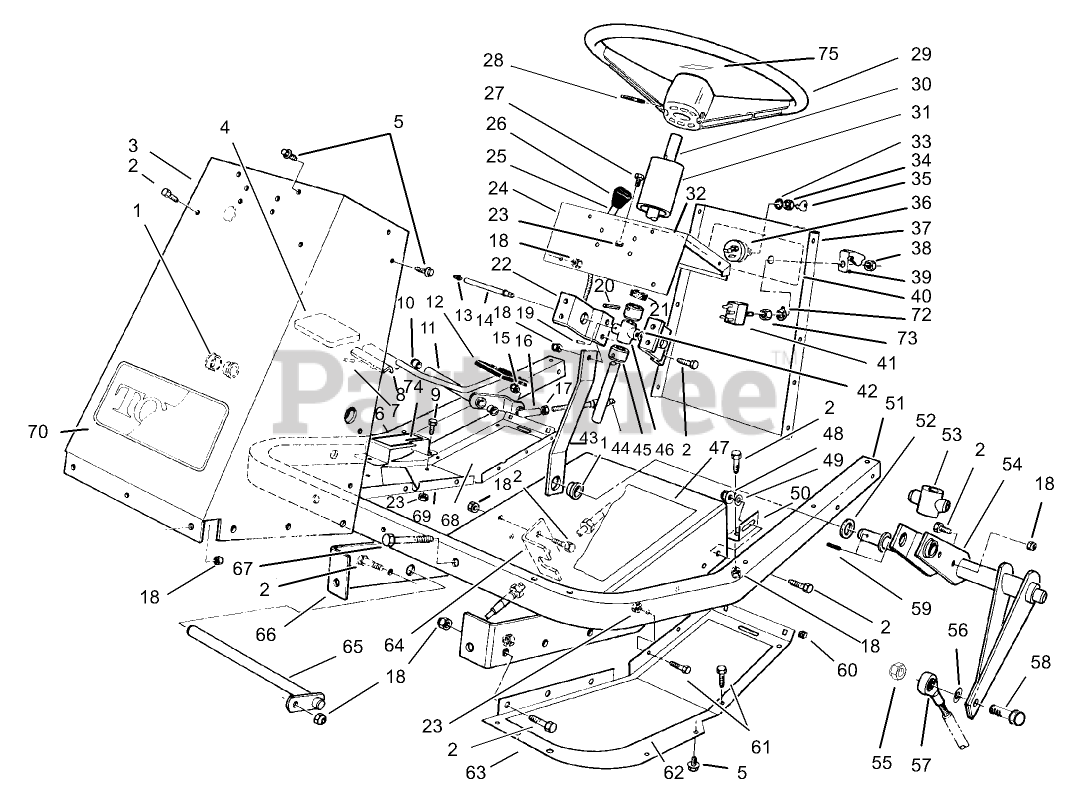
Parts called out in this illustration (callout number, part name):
1	BEARING-FLANGE
2	SCREW-HH
3	Tower-Front
4	FORWARD PEDAL PAD
5	SCREW-HHFTF
6	Footrest-Pedal
7	PIN-ROLL
8	ACCELERATOR PEDAL
9	SCREW-HH
10	BUSHING-FLANGE
11	Pedal-Traction (Incl. Ref. #10)
12	REVERSE PAD
13	FITTING-GREASE
14	TUBE ZERK
15	NUT-LOCK
16	JOINT-BALL
17	NUT-JAM
18	NUT-LOCK, NI
19	3/32 X 9/16 ROLL PIN
20	PIN-SPRING
21	COVER-DUST
22	BRG SUPT BRKT
23	NUT-LOCK, NI
24	Tower-Top
25	CONTROL-CHOKE,THROTTLE
27	SCREW-HH
28	PIN-ROLL
29	STEERING WHEEL ASM
30	Shaft-Steering
31	STRG. SHAFT COVER
32	THROTTLE DECAL
33	WASHER-TOOTH, INTERNAL
34	NUT-HH
35	KEY-IGNITION
36	Switch-Ignition (Incl. Ref. #33-34)
37	Panel-Tower Rear
39	COVER-PTO SWITCH
40	SWITCH DECAL
41	Switch-Clutch & Brake (Incl. Ref. # 38, 72 & 73)
42	WASHER-BELLEVILLE
43	Link-Steering
44	TRACT CONT.CABLE
45	STRG SHAFT COLLAR
46	BRG STEERING SHAFT
47	TUNNEL DECAL
48	NUT-HF
49	WASHER-PLAIN
50	TUNNEL BRKT
51	Frame-Footrest
52	WASHER-THRUST
53	STEER.SHAFT FOLLOWER
54	Follower Lever
55	NUT-LOCK, NI
56	WASHER-FLAT
57	BALL JOINT LH
58	SCREW-HH
59	PIN-ROLL
60	NUT-RETAINED
61	SCREW-HH
62	FOOT REST PAD LH
63	Footrest-L.H.
64	TRACT CABLE BRKT
65	PEDAL.SHAFT WA
66	Tunnel
67	SCREW-HH
68	FOOT REST PAD RH
69	Footrest-R.H.
70	DECAL
72	TAB-WASHER
73	NUT-HEX, SPECIAL
74	FOOTREST PAD
75	DECAL
